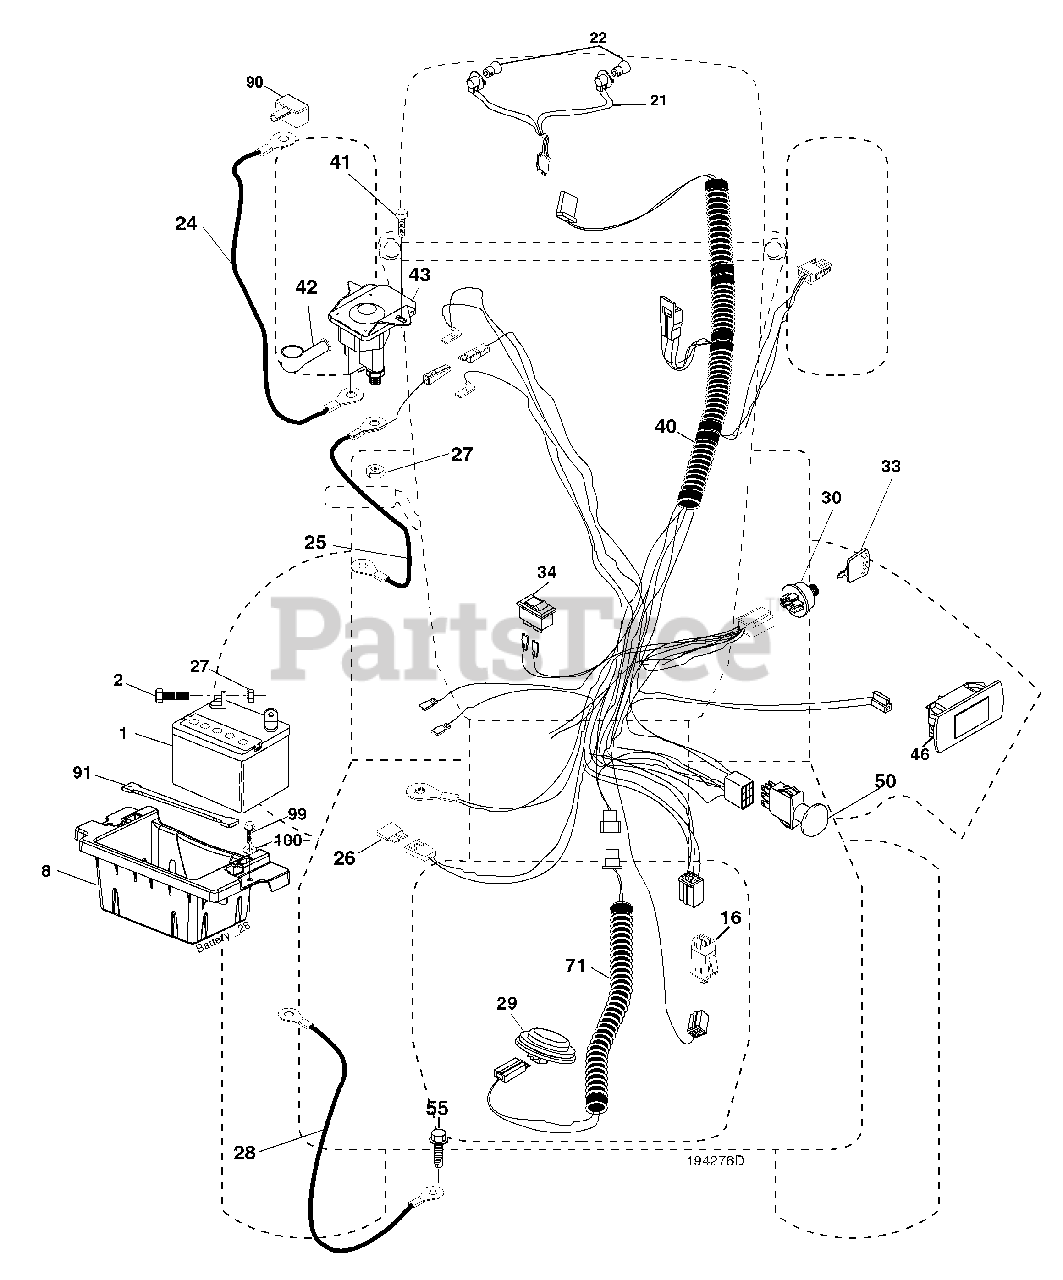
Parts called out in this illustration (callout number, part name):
1	Battery
2	Bolt Hex Head 1/4-20 x 3/4
8	Box Battery
16	Switch Interlock Push-In
21	Harness Socket Light W/4152J
22	Bulb Light
24	Cable Brty
25	Cable Starter
27	Nut Keps Hex 1/4-20 unc
28	Cable, Ground
29	Switch, Seat
30	Switch, Ign
33	Key, Ignition
34	Switch Light / Reset
40	Harness Ign.
41	Screw Thd Cut 1/4-20 x 1/2
42	Cover, Terminal
43	Solenoid
46	Gauge Servicereminder Hrmtr
50	Switch PTO
55	Screw Thdrol 5/16-18 x 3/4 TYTT
71	Harness Ign. Dash
90	Cover Terminal
91	Strap Battery Mount Front
99	Screw Hexwsh Thdrol 1/4-20 x 3/4
100	Washer 9/32 x 7/8 x 16 Ga.
100	Harness Pigtail
